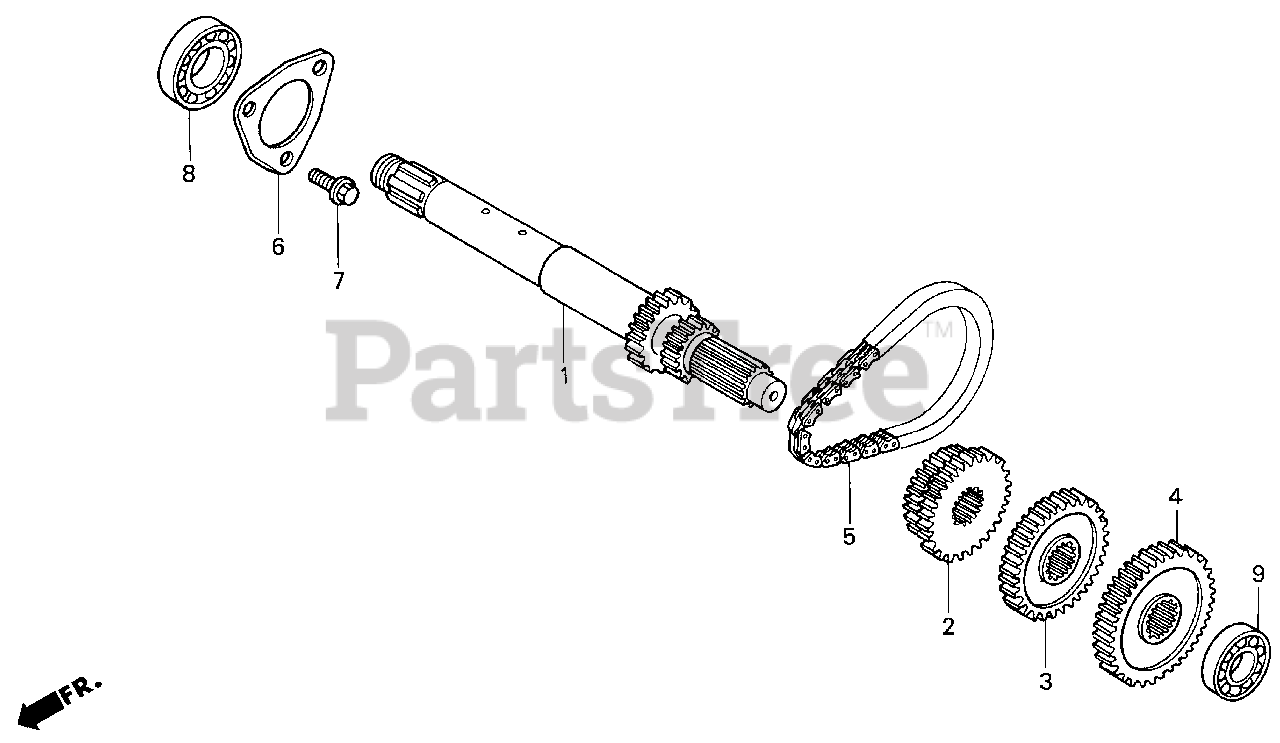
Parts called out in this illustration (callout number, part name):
2	GEAR, MAINSHAFT SECOND & THIRD (30/23T)
3	GEAR, MAINSHAFT FOURTH (34T)
4	GEAR, MAINSHAFT FIFTH (37T)
5	CHAIN, REVERSE
5	CHAIN, REVERSE (SC-A-0412-52)
6	HOLDER, BEARING
7	BOLT, FLANGE (6X16)
8	BEARING, RADIAL BALL (6004)
9	BEARING, RADIAL BALL (6202)
